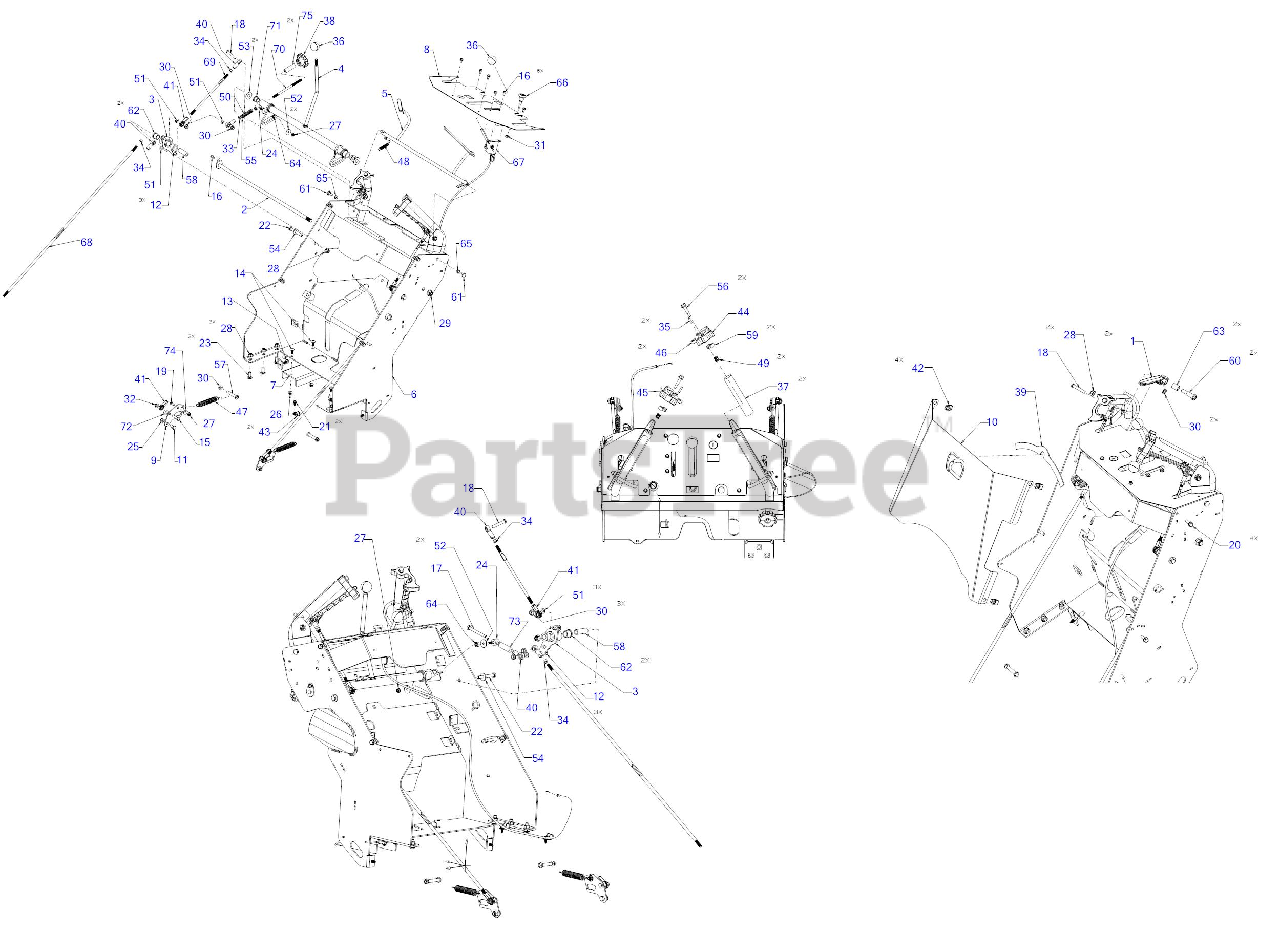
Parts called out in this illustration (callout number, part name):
2	PIVOT CONTROL WELDMENT
3	BELLCRANK ASSEMBLY
4	CRUISE CONTROL ASSEMBLY
6	HANDLE CONTROL ASSEMBLY
7	PEDAL BRACKET
8	CONTROL PANEL
9	TRANSMISSION CONTROL BRACKET
10	UPPER HANDLE COVER
11	HEX SCREW 3/8-16 x .75
12	CARRIAGE BOLT 5/16-18 x 1.00
13	SCREW 5/16-18 x .750
14	CARRIAGE BOLT 5/16-18 x .75
15	SCREW 5/16-18 x 1.25 GR5
16	SCREW 1/4-20 X.500
17	SCREW (5/16-24:3.00:GR5)
18	SCREW (5/16-18:1.7)
19	SCREW 1/4-20 x .75 GR5
20	SCREW 5/16-18 x .875 GR5
21	SCREW 1/4-20X.625
22	SCREW 3/8-16 x 2.75 GR5
23	CARRIAGE BOLT 3/8-16 x 1.00 GR5
24	FURRLE (.328 ID X .250)
25	HEX NUT INS L-3/8-16
26	FLANGE LOCK NUT 5/16-18
27	FLANGE LOCK NUT
30	FLANGE NUT
31	HEX JAM NUT 3/8X24
32	HEX FLANGE NUT
33	HEX JAM NUT 5/16-24 GR 5
34	NUT-5/16X 24
35	DOWEL PIN
37	GRIP (1.0 ID X 5.5 X .065)
38	KNOB (5/16-24) (LH)
39	BLOWER HOUSING SEAL
40	ROD END 5/16 ID
41	END ROD- 5/16 (LH)
42	U-NUT
44	HANDLE LOCK (RH)
45	HANDLE LOCK (LH)
46	NEUTRAL LOCK ROLLER
47	EXTENSION SPRING
48	EXTENSION SPRING
49	NEUTRAL LOCK SPRING
50	TRACKING SPRING
51	FLAT WASHER
52	FLAT WASHER
53	FLAT WASHER (0.526X1.250X0.048)
55	FLAT WASHER ID-.320 x .598
56	SHOULDER SCREW
57	SHOULDER SCREW
58	BELLCRANK SPACER
59	NEUTRAL LOCK SPACER
60	SHOULDER SCREW .50X.925
61	SHOULDER SCREW .375X.380:1/4-20
62	FLANGE BEARING
63	SLEEVE BEARING .623 x .5025 x .250
64	BALL BEARING .25 x .625 SPCL
65	FLANGE BEARING
66	CHOKE CABLE
67	THROTTLE CABLE
68	TRANSMISSION CONTROL ROD
69	CONTROL LEVER ROD
70	CONTROL TRACKNG ROD
71	FLANGE BEARING
72	IDLER BRACKET SPACER .340X.750X.330
73	SPACER (.322 X .625 X 1.8)
74	TRANSMISSION SPACER
